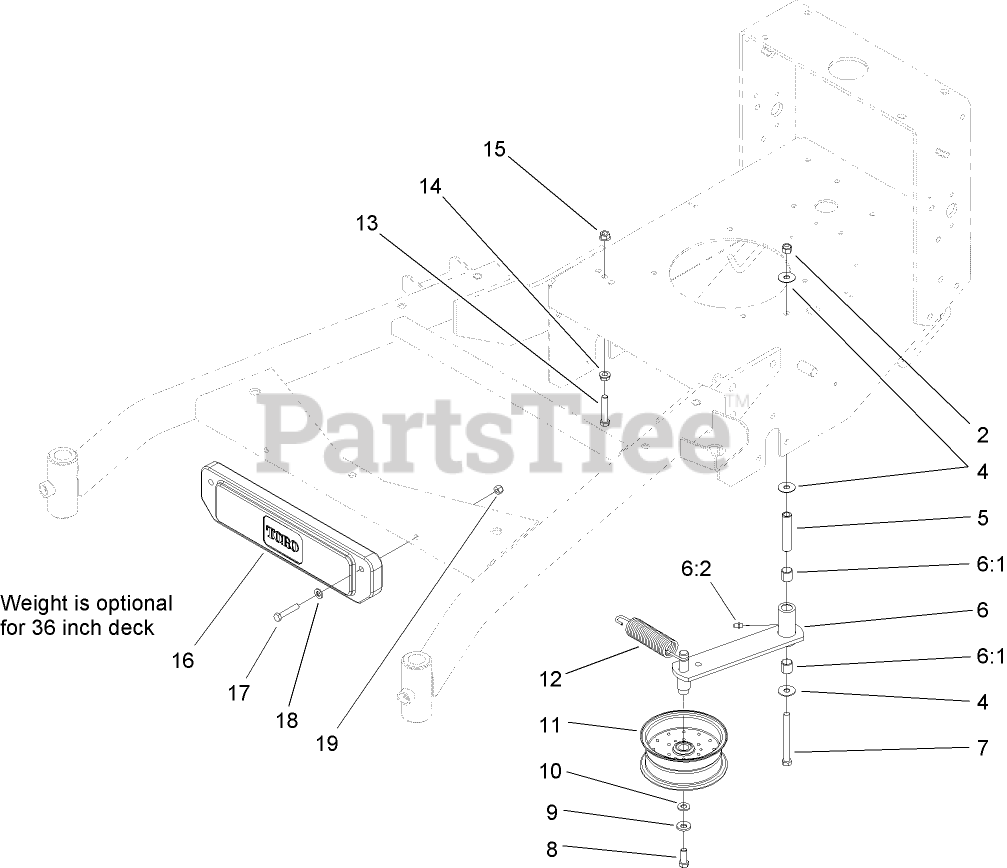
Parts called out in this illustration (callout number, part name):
2	NUT-LOCK, NI
4	WASHER
5	TUBE-IDLER
6	IDLER ARM ASM
6:1	SLEEVE-BEARING
6:2	FITTING-GREASE
7	SCREW-HH
8	SCREW-HH
9	WASHER-BELLEVILLE
10	WASHER-FLAT
11	PULLEY-IDLER
12	SPRING-EXTENSION
13	SCREW-HH
14	NUT-HHF, WHIZ
15	NUT-HF
16	WEIGHT-CAST
17	SCREW-HH
18	WASHER-PLAIN
19	NUT-LOCK, NI
